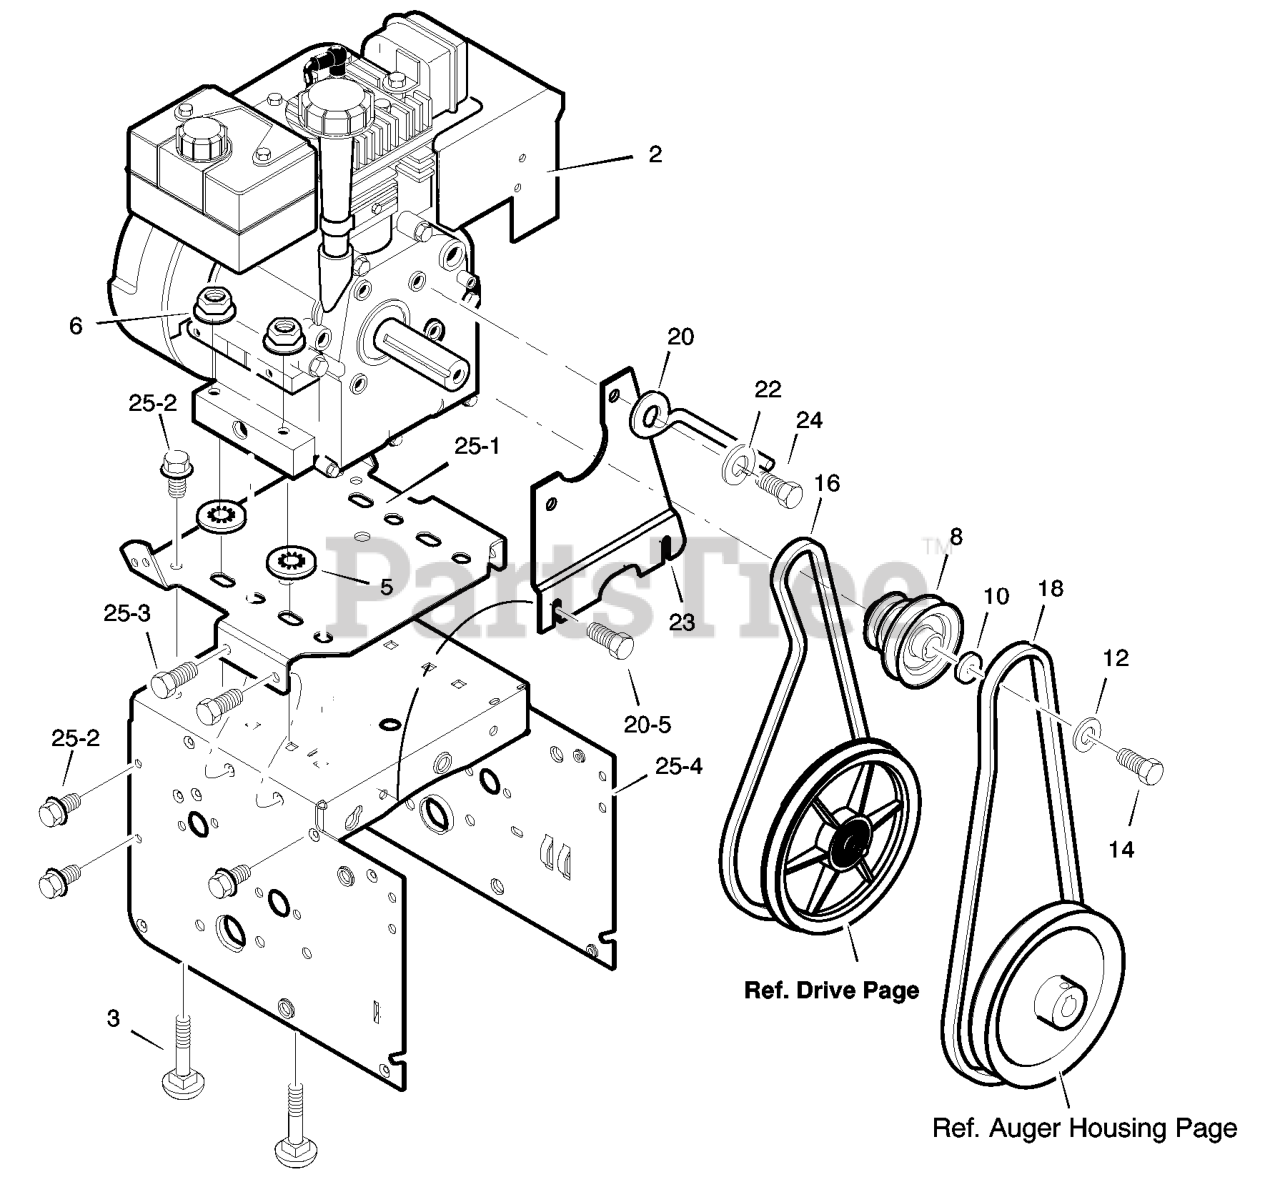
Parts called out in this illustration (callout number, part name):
2	ENGINE
3	BOLT, CARRIAGE 5/16-18
5	RETAINER, PUSH
6	NUT, HEX 5/16-18
8	PULLEY, ENGINE
10	WASHER
12	WASHER .38ID
14	SCREW, 3/8-24 x 1.00
16	BELT, V 3L 33.13LG
18	BELT, V 4L 38.1MF16" 5-10
20	GUIDE, BELT
22	WASHER, SPTLK .31X.58X.08
23	PLATE, ANTI VIBRATION
24	SCREW, 5/16-24 x 1.00
25	FRAME ASSEMBLY
25-1	PLATE, ENGINE MOUNT
25-2	SCREW, TAP 1/4-20 X .63
25-3	SCREW, TAP 5/16-18 X .50
25-4	FRAME, MOTOR BOX
